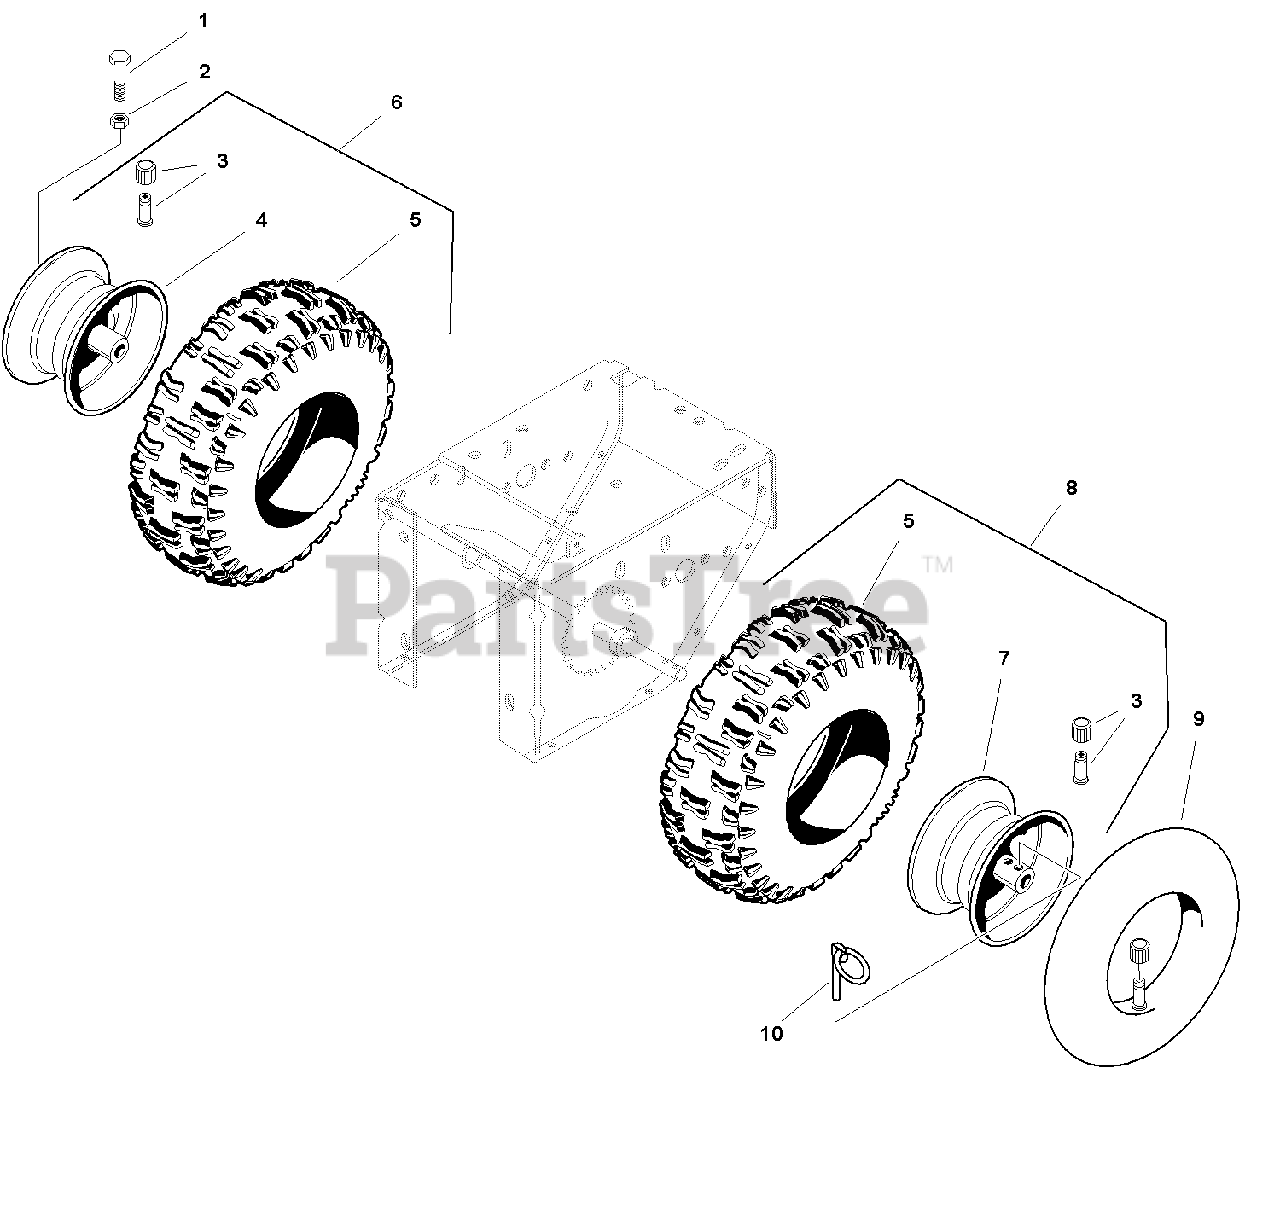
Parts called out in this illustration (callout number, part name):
1	KLIK-PIN
3	VALVE STEM & CAP
5	TIRE, 16 x 6.50-6
6	WHEEL & TIRE ASSEMBLY, RH (Includes Ref. Nos. 3, 4 & 5)
7	HUB, Wheel, LH
8	WHEEL & TIRE ASSEMBLY, LH (Includes Ref. Nos. 3, 5 & 7)
